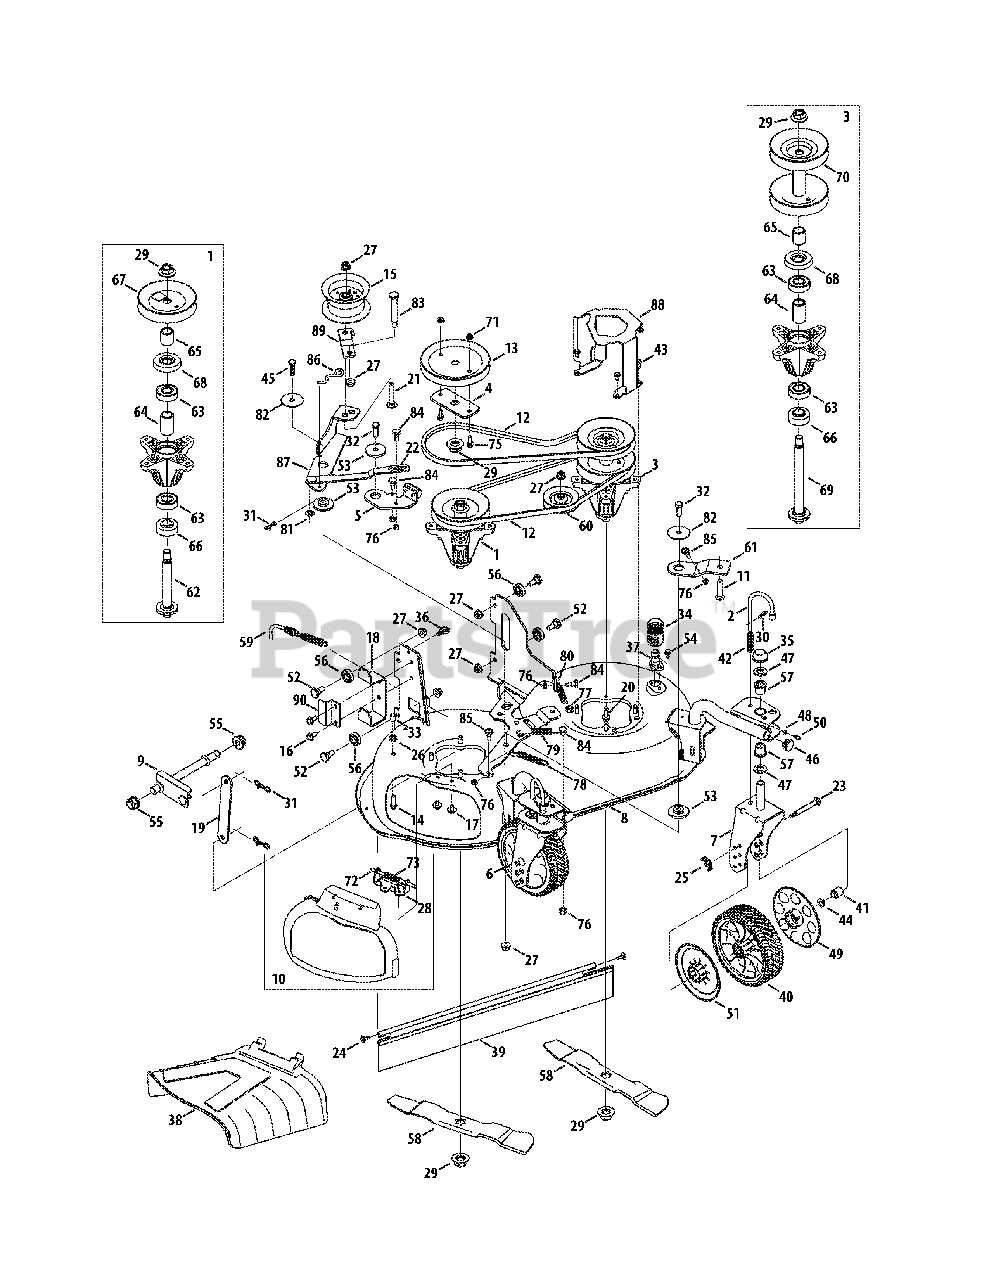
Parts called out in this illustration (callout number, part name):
1	Spindle Assembly, 5.08 Dia.
3	Spindle Assembly, 5.08 Dia.
4	Spacer, .79 x 1.25 x .175
5	Deck Bracket Assembly
6	Caster Bracket Assembly RH
7	Caster bracket Assembly LH
9	Deck Lift Assembly
10	Mulch Plug Assembly
11	Carriage Bolt, 3/8-16 x 1.75
12	Belt, A-Section, 43.10
13	Drive Pulley, 6.03 Dia.
14	Hex Cap Screw, 5/16-18 x 1.00
15	Idler Pulley, 3.125 OD
16	Hex Washer Screw, 5/16-18 x .750
17	Screw, 1/4-20 x .500
18	Grassbag Bracket
19	Lift Link Bracket
20	Self-Tapping Screw, 5/16-18 x 1.00
21	Carriage Bolt, 3/8-16 x 2.25
22	Brake weld Assembly
23	Caster Axle
24	Screw, #10-16 x .625"
25	Wing Nut, 1/4-20
26	Flange Lock Nut, 5/16-18
27	Flange Lock Nut, 3/8-16
28	Chute Bracket
29	Hex Flange Nut, 5/8-18
30	Cotter Pin, .072 Dia. x 1.13 Lg.
31	Bow-Tie Cotter Pin
32	Hex Cap Screw, 3/8-16 x 1.00
33	Cap, .290 x .500
34	Water Nozzle Adapter
35	Push Cap, 5/8
36	Cable Retainer Clip
37	Deck Wash Nozzle
38	Chute Deflector
39	Trailshield
40	Front Wheel, 7 x 2
41	Caster Hub, Long
42	Compression Spring, .531 x 1.75 Lg.
43	Hex Washer Screw, 1/4-20 x .500
44	Caster Hub, Short
45	Hex Screw, 3/8-16, 1.25, Gr5
47	Flat Washer, .640 x 1.12 x .125
48	Flat Washer, .200 x .370 x .060
50	Grease Fitting, 3/16
51	Dust Cover, 7"
52	Shoulder Screw, 3/8-16 x .496 x .336
53	Shoulder Spacer, .884 x .190
54	Shoulder Screw, 1/4-20 x 0.50
55	Hex Flange Bearing
56	Ball Bearing, 50 x 1.125 x .312
57	Flange Bearing, .631 ID
58	Blade
59	Clutch Cable
60	Idler Pulley, V-Type x 3.06
61	Idler Bracket
62	Spindle Shaft, 6.11 Long
63	Ball Bearing
64	Spacer, .792 x 1.060 x 1.860
65	Spacer, .795 x 1.062 x 1.015
66	Spacer, .79 x 1.82 x .79
67	Deck Pulley
68	Bearing Shield
69	Spindle Shaft, 8.27 Long
70	Pulley Spindle Assembly, 5.08 Dia.
71	Flange Lock Nut, 1/4-20
73	Torsion Spring
75	Hex Flange Screw, 1/4-20 x .75
76	Hex Lock Nut, 1/4-20
77	Hex Lock Nut, 3/8-16, Centerlock
78	Extension Spring, .5 x 3.97
79	Extension Spring, .500 Dia. x 4.233
80	Extension Spring, .500 Dia. x 3.445
81	Flat Washer, .375 x .738 x .063
82	Flat Washer, .406 x 1.92 x .060
83	Shoulder Screw, .5 x 2.62, 3/8-16
84	Shoulder Screw, .375 x .380, 1/4-20
85	Shoulder Screw, .375 x .280, 1/4-20
86	Spring Hook Rod
87	Drive Bracket
